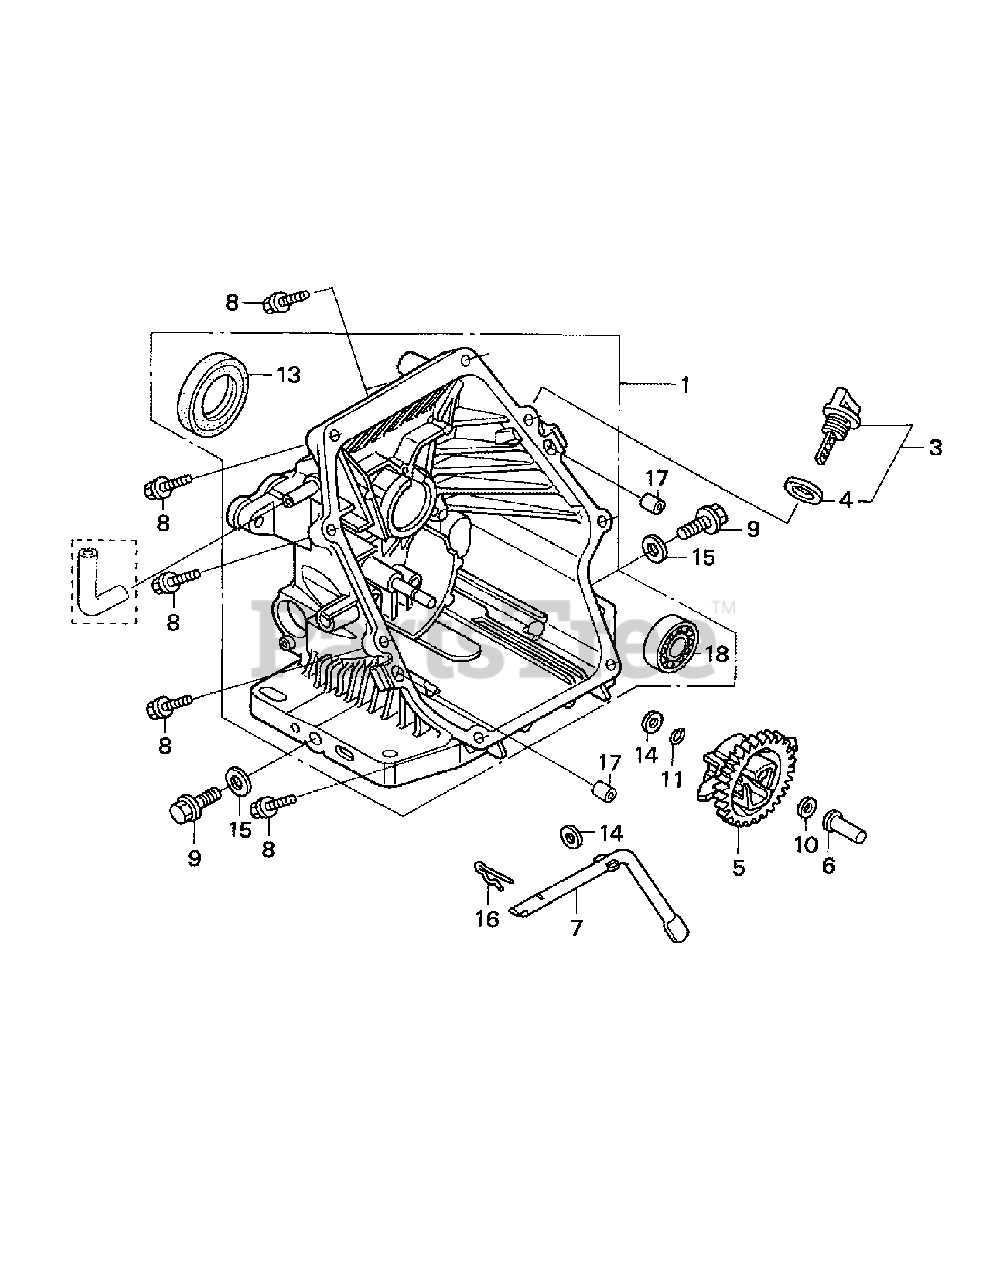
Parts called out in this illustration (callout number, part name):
1	Crankcase Cover Assembly
3	Oil Filler Cap Assembly
4	Oil Filler Cap Gasket
5	Governor Assembly
6	Governor Slider
7	Governor Arm Shaft
8	Flange Bolt, 6 x 25
9	Drain Plug Bolt
10	Thrust Washer, 6mm
11	Governor Holder Clip
13	Oil Seal, 28 x 41.25 x 6
14	Plain Washer, 6mm
15	Drain Plug Washer, 12mm
16	Lock Pin, 8mm
17	Dowel Pin, 8 x 20
